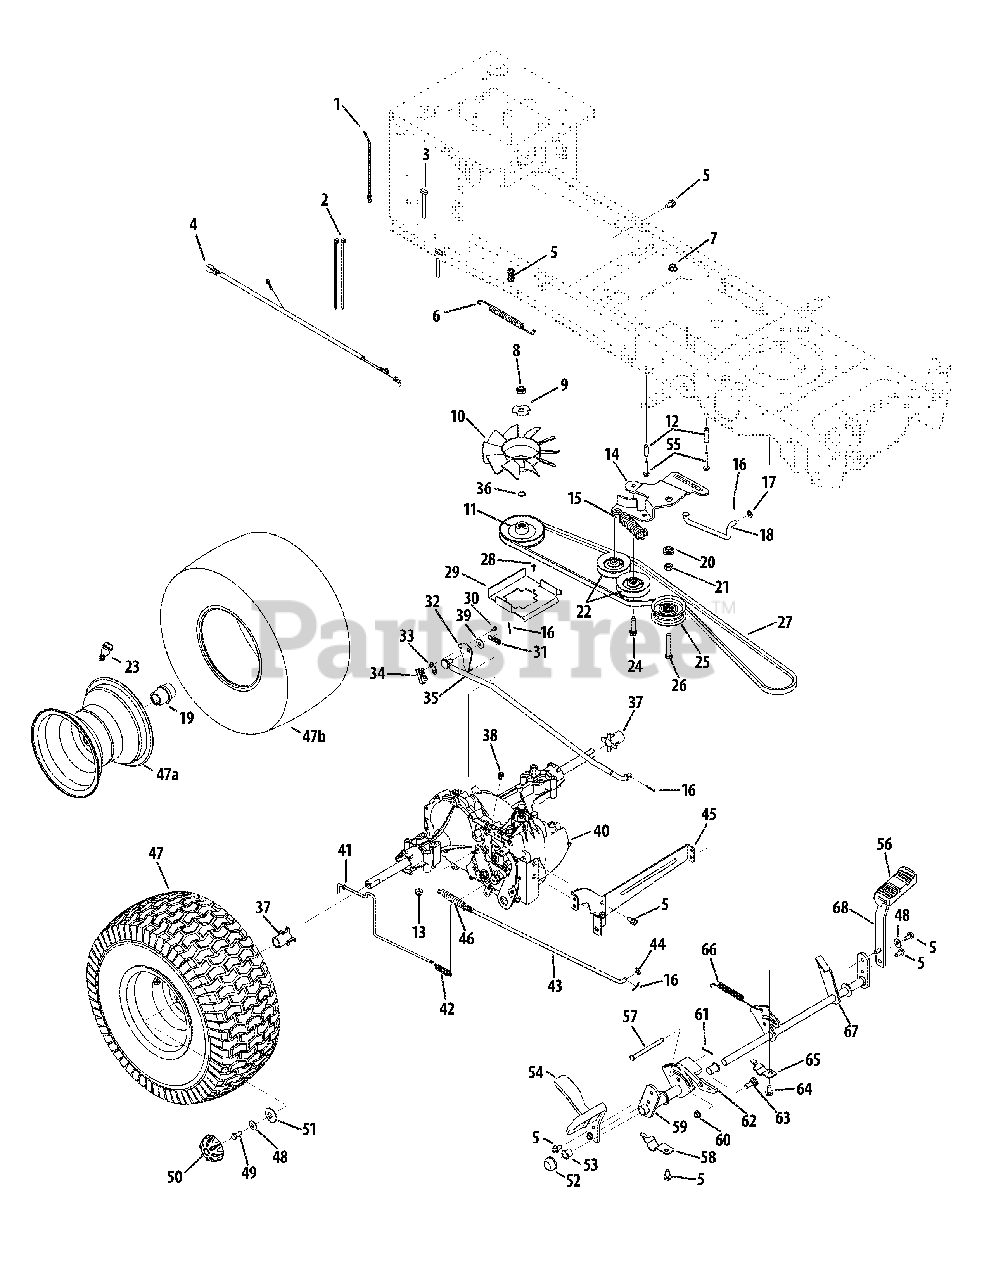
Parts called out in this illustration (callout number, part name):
1	Cable Tie, 7.5
2	Cable Tie, 3/16 x .05 x 7.4
3	Hex Bolt 5/16-18 x 2.75
4	Jumper Harness
5	S-Tapp Scr 5/16-18 x .75
6	Extension Spring .50 dia. x 12.6
7	Flange Locknut 3/8-16 Gr. F
8	Jam Locknut 1/2-10
12	Spacer, .260 x .372 x 1.420
13	Flange Locknut 5/16-18 Gr. F, Nylon
14	Idler Bracket
15	Extension Spring .59 x 4.0
16	Cotter Pin 3/32 dia x 1.00 Lg.
17	Flat Washer .330 x .630 x .0635
18	Pedal Transmission Bypass Rod
20	Shoulder Spacer 1.375 x .38 x .183
21	Hex Jam Nut 7/16-20
24	Hex L-Wash HD Scr 3/8-16 x 1.5
25	Idler Pulley, Flat 2.75 OD
26	Hex Bolt 3/8-16 x 2.25" Lg.
28	Truss Mach B-Tapp Scr #10 X .50
29	Belt Disengage Support Bracket
30	Hex Washer Screw #8-18 x .50
31	Extension Spring 3/8 x 1.44
32	Switch Actuator Bracket
33	Insulator Nut Plate
34	Short Spring Switch
35	Hydro Control Rod
37	Sleeve 0.765 x 1.5
38	Hex Wash HD Tapp Scr 1/4-20 x .375
39	Flat Washer .406 ID x .812 OD x .134
40	Hydro Transmission
41	Hydro Bypass Rod
42	Extension Spring .47 OD x 2.03 Lg.
44	Flat Washer .312 ID x .75 OD
45	Hydro Mount Bracket
46	Extension Spring .59 x 4.0
47	Wheel Ass'y Comp. 20 x 8 x 8
48	Cupped Washer .345 ID x .88 OD x .060
49	Hex L-Bolt 5/16-24 x .75 Gr. 5
50	Hub Cap
51	Flat Washer, .350 x 1.59 x .062
52	Push Cap 5/8" Dia Rod
53	Nyliner Flanged Brg.
55	Hex Washer Hd. TT Screw 1/4-20 x 1.625
56	Brake Pedal Pad
57	Clevis Pin 5/16 x 3.985
58	Transmission Rod Support Strap
59	Hydro Pedal Brkt. Assembly
60	Flange Lock-Nut 3/8-16 Gr. F Nylon
61	Bow-Tie Cotter Pin
63	Shoulder Screw .500 x .25
64	Self-tapping Screw 5/16-18 x .625
65	Brake Shaft Support Strap
66	Extension Spring .63 x 4.95
67	Brake Control Assembly
68	Brake Pedal Bracket
